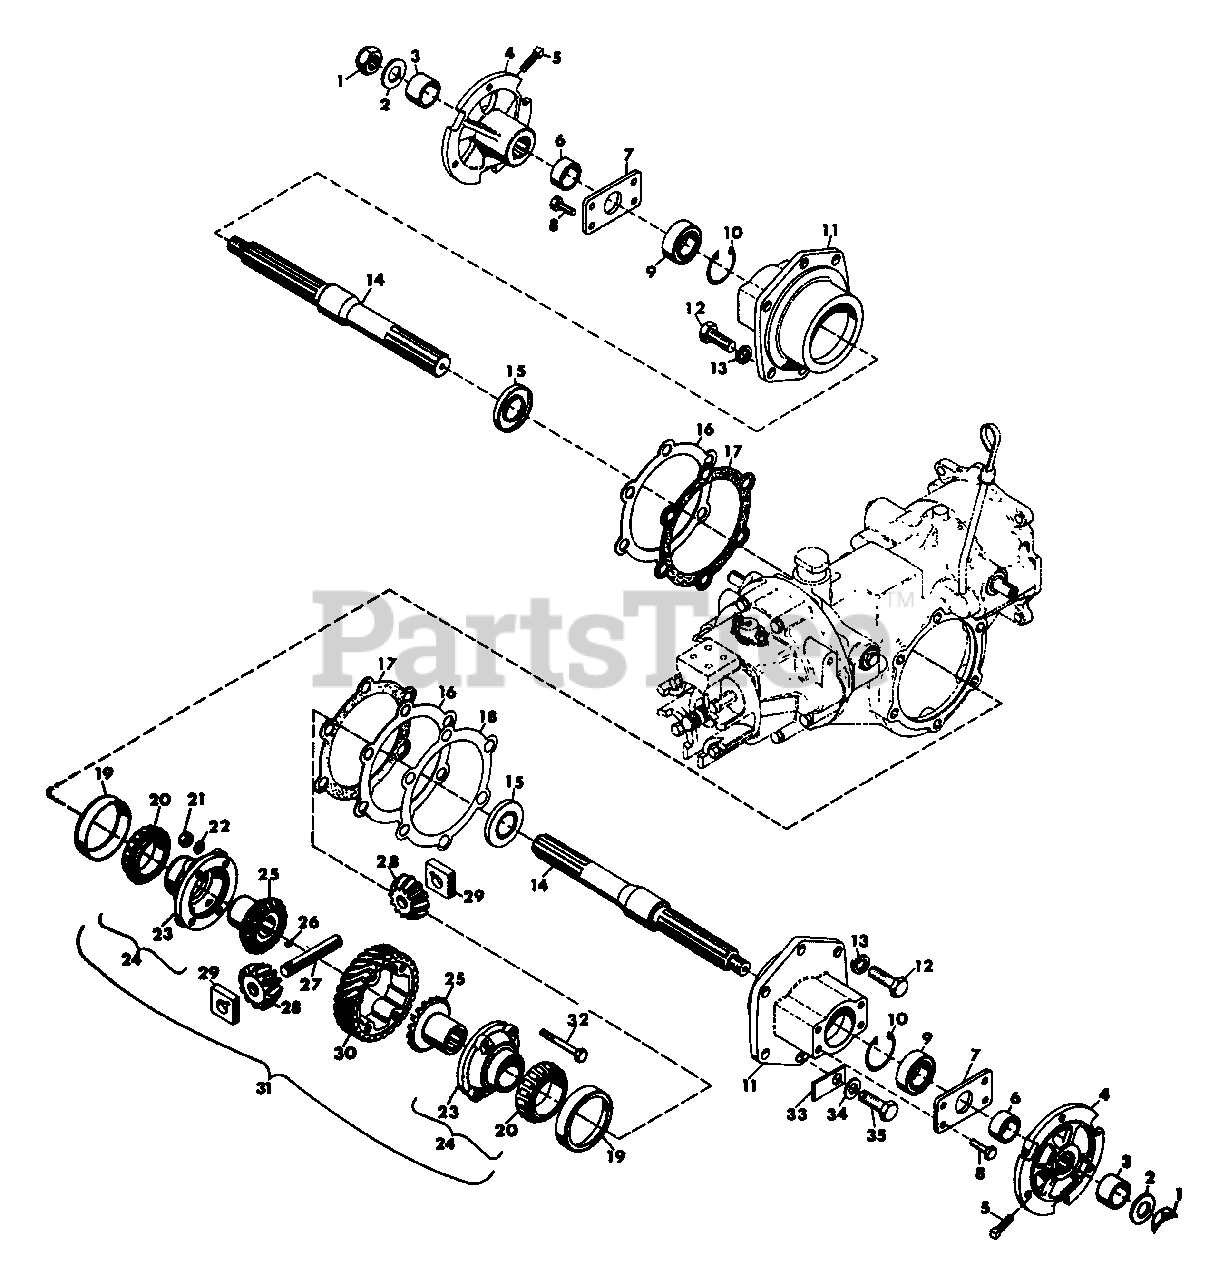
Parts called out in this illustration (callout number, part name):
1	Nut-Hex 3/4-10 Light Thin
2	Washer, Flat .812 x 1.469 x .134
3	Spacer
4	Hub, Wheel
5	Screw, Set 7/16-14 x 1.00
6	Spacer
7	Plate, End
8	Bolt-Hex 3/8-16 x .750
9	Bearing-Ball 1.00 x 2.00 x .562
10	Ring-Retaining 2.00 Bore
11	Housing, Axle
12	Bolt-Hex 1/2-13 x 1.00
13	Washer-Lock 1/2 Reg.
14	Axle-Straight
15	Seal-Oil 1.188 x 2.00 x .250
16	Shim-Axle Housing .005
17	Gasket-Axle Housing
18	Shim-Axle Housing .020
19	Cup, Roller Bearing
20	Cone, Roller Bearing
21	Nut, Hex 5/16-24
22	Washer, Lock 5/16 Internal Tooth
23	Housing, Differential
24	Assembly, Differential Housing
25	Gear, Differential Bevel
26	Key, Woodruff .125 x .375 Hard
27	Pin, Spider Pinion
28	Gear, Spider Bevel
29	Block, Drive
30	Gear, 6 Lead Worm
31	Assembly, Differential Standard 6 Lead
32	Bolt, Hex 5/16-24 x 2.75
33	Washer, Oil Drain
34	Washer, Flat .531 x 1.062 x .095
35	Bolt, Hex 1/2-13 x 1.00 Nylon Insert
